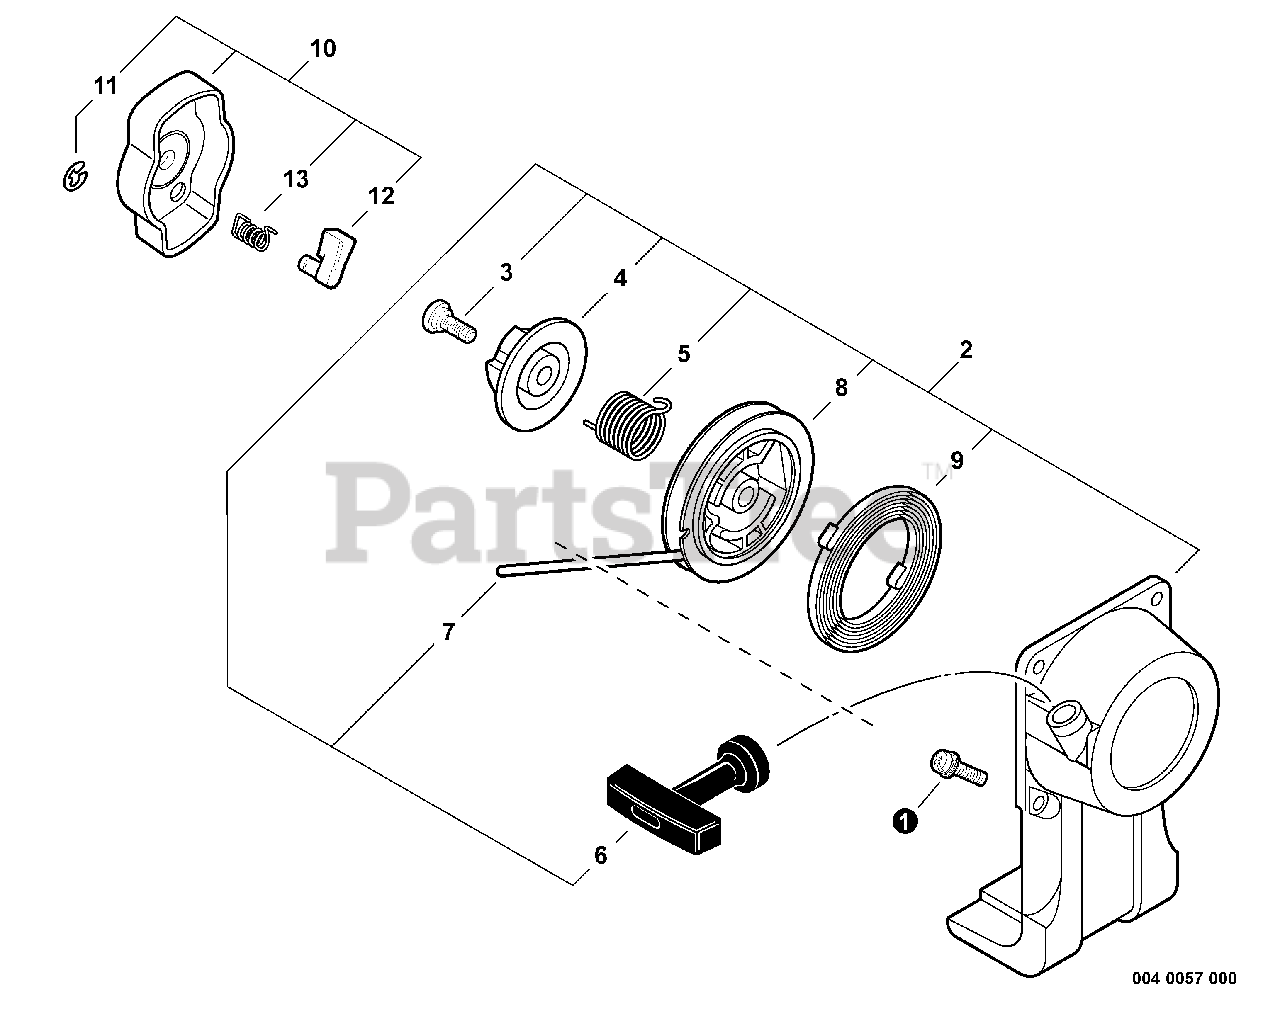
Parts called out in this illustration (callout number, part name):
1	SCREW 4×16
2	STARTER ASSY, RECOIL
3	SCREW
4	PLATE, CAM (NLA SEE PB 15-06)
5	SPRING, TORSION
6	GRIP, STARTER
7	ROPE, STARTER
8	REEL, ROPE
9	SPRING, RECOIL
10	PAWL ASSY, STARTER
11	E-RING 4
12	PAWL, STARTER
13	SPRING, RETURN
